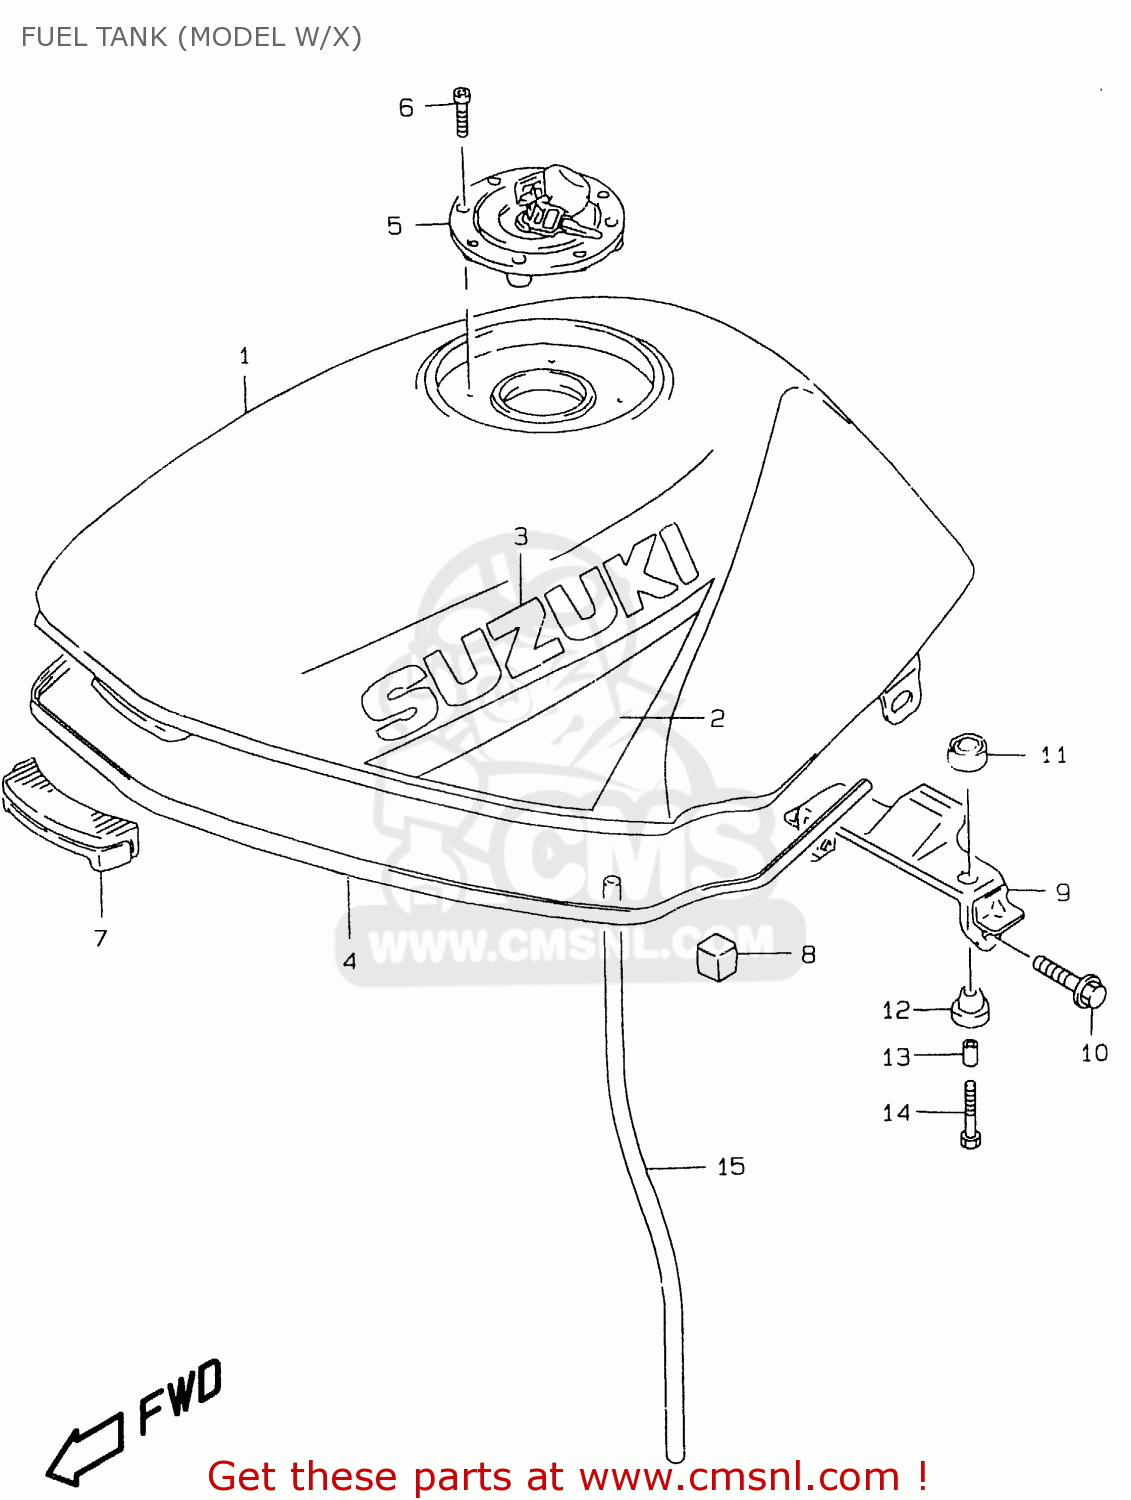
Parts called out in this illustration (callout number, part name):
1	TANK ASSEMBLY,FUEL
2	TAPE SET,FUEL TANK
3	EMBLEM,FUEL TANK
4	MOLDING
5	CAP SET,FUEL TANK
6	BOLT(5X20)
7	CUSHION,FUEL TANK FR
8	CUSHION,FUEL TANK SIDE
9	BRACKET COMP,FUEL TANK
10	BOLT
11	CUSHION
12	CUSHION
13	SPACER(6.5X9X18)
14	BOLT(6X30)
15	HOSE,WATER DRAIN
